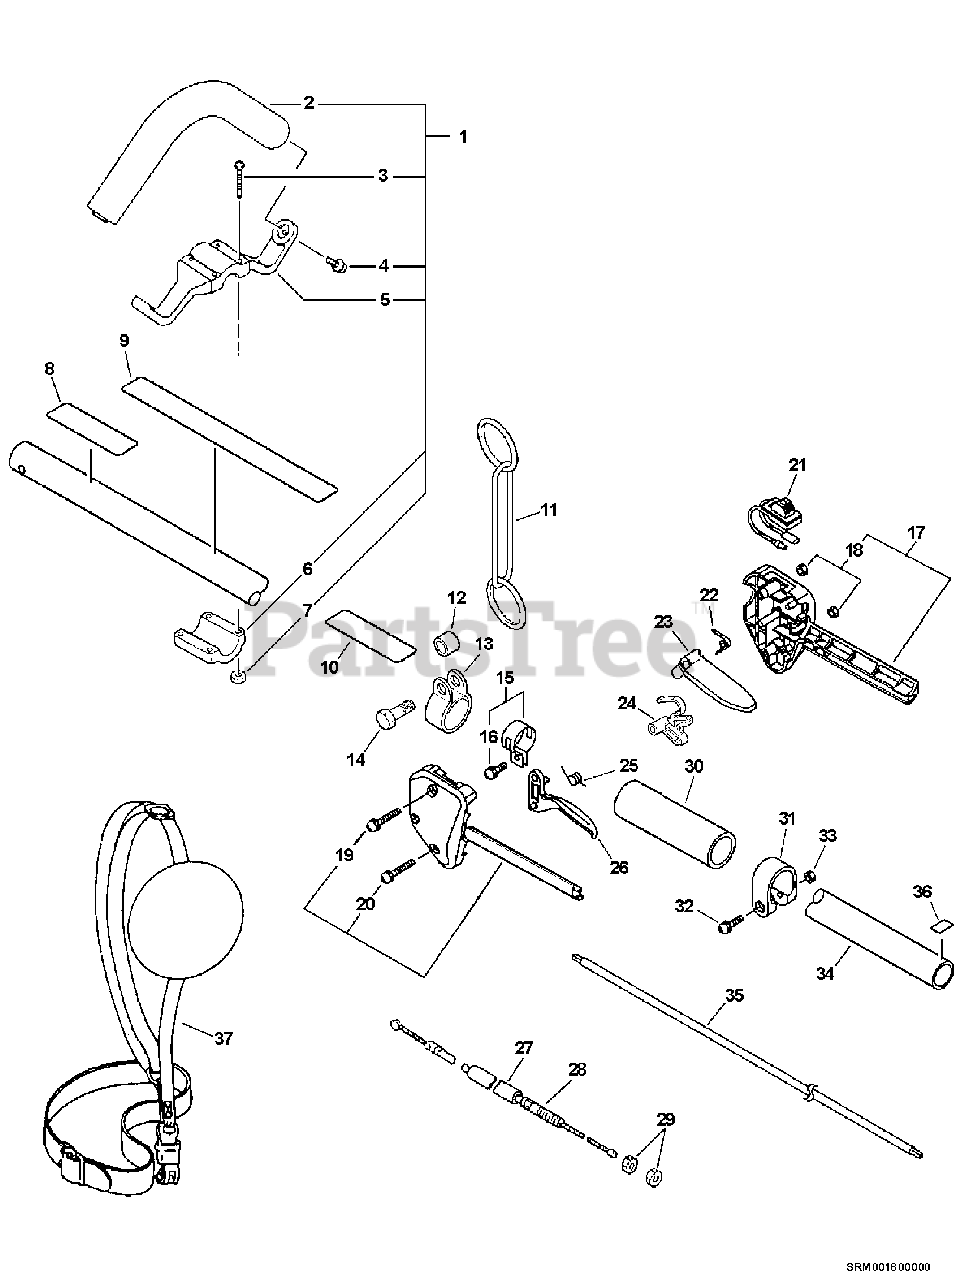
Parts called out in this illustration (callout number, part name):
1	HANDLE ASSY
2	HANDLE
3	SCREW 5×35
4	SCREW 5×14
5	BRACKET, HANDLE
6	BRACKET, HANDLE
7	NUT M5
8	LABEL, CAUTION
9	LABEL, CAUTION
10	LABEL, HANDLE LOCATION
11	HOOK
12	SPACER, GUARD
14	BOLT 5×18
15	HANGER ASSY
16	SCREW 5×14
17	BRACKET, THROTTLE
18	NUT M5
19	SCREW 5×35
20	SCREW 5×25
21	SWITCH, ON-OFF
22	SPRING, TORSION
23	LEVER, THROTTLE LOCKOUT
24	LOCKOUT, THROTTLE
25	SPRING, TORSION
26	TRIGGER, THROTTLE
27	TUBE - VINYL
28	CABLE, THROTTLE
32	SCREW 5×28
33	NUT M5
34	PIPE, MAIN
35	DRIVESHAFT
36	LABEL - ALIGNMENT
37	SHOULDER STRAP ASSY
